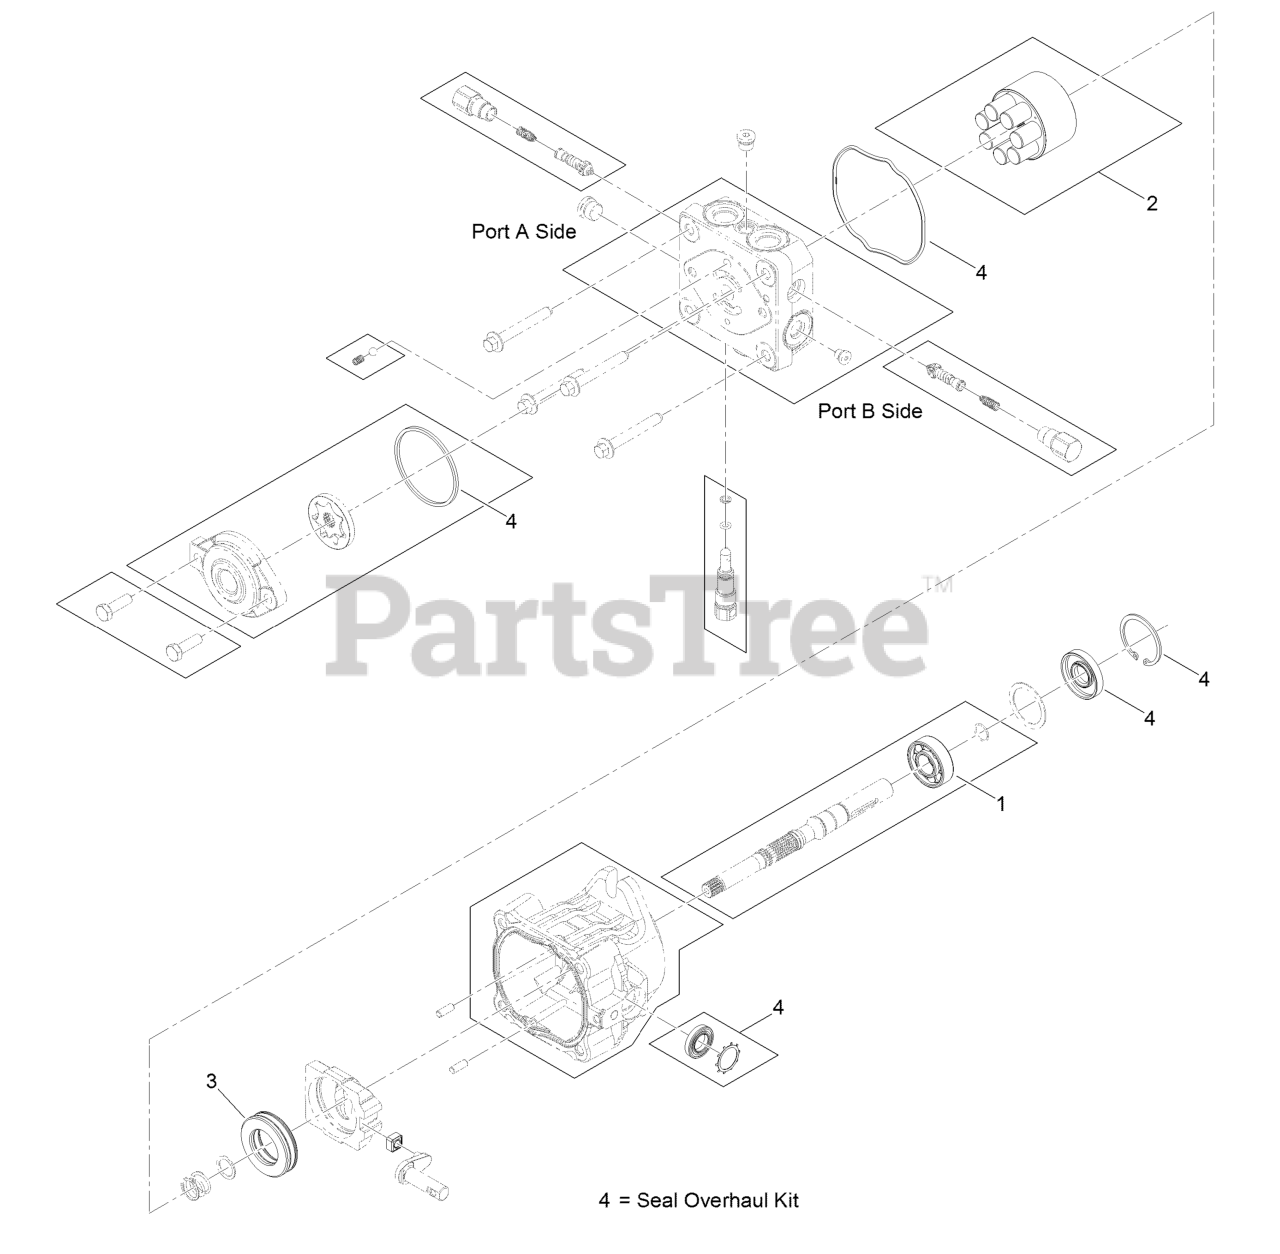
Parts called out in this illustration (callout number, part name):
1	Bearing-Ball
2	Cylinder Block Kit
3	Bearing-Thrust, Plastic Cage
4	Seal Overhaul Kit
